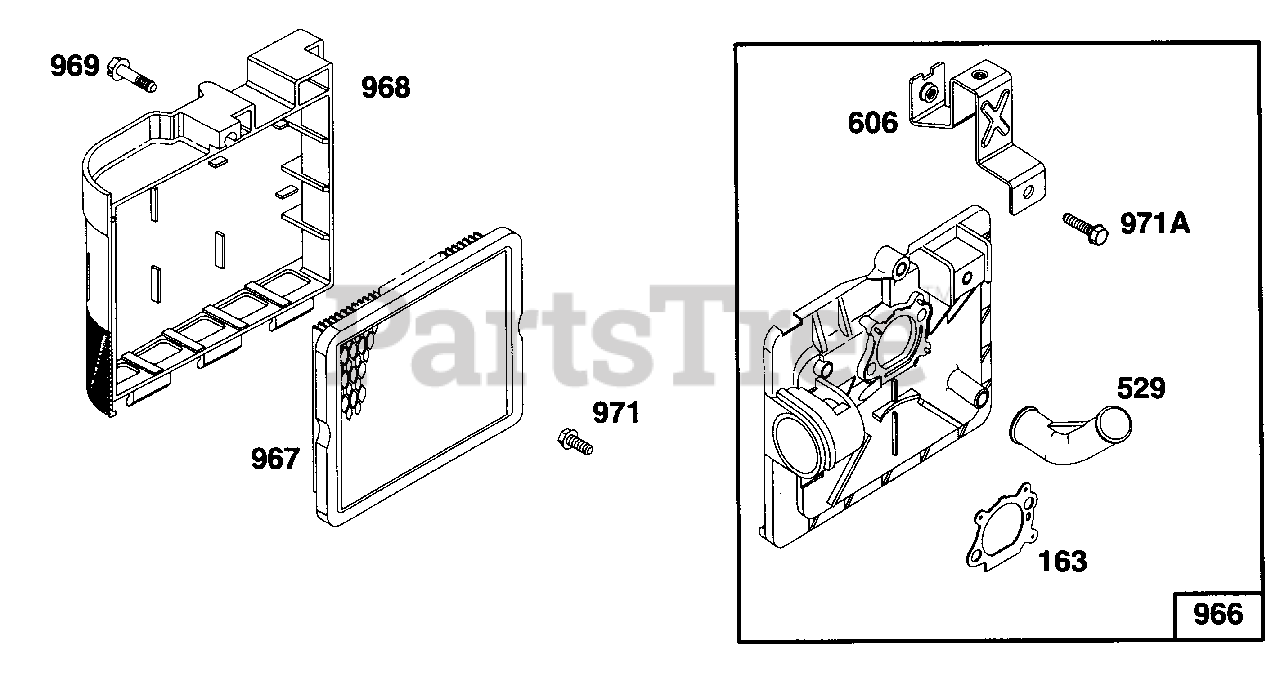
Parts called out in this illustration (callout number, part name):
163	Gasket-Air Cleaner
529	Grommet-Breather
606	Strap-Bracket
966	Base-Air Cleaner
967	Filter-Air
968	Cover-Air Cleaner
969	Screw-Cover Mtg.
971	Screw-Air Cleaner
971A	Screw-Hex. Head
